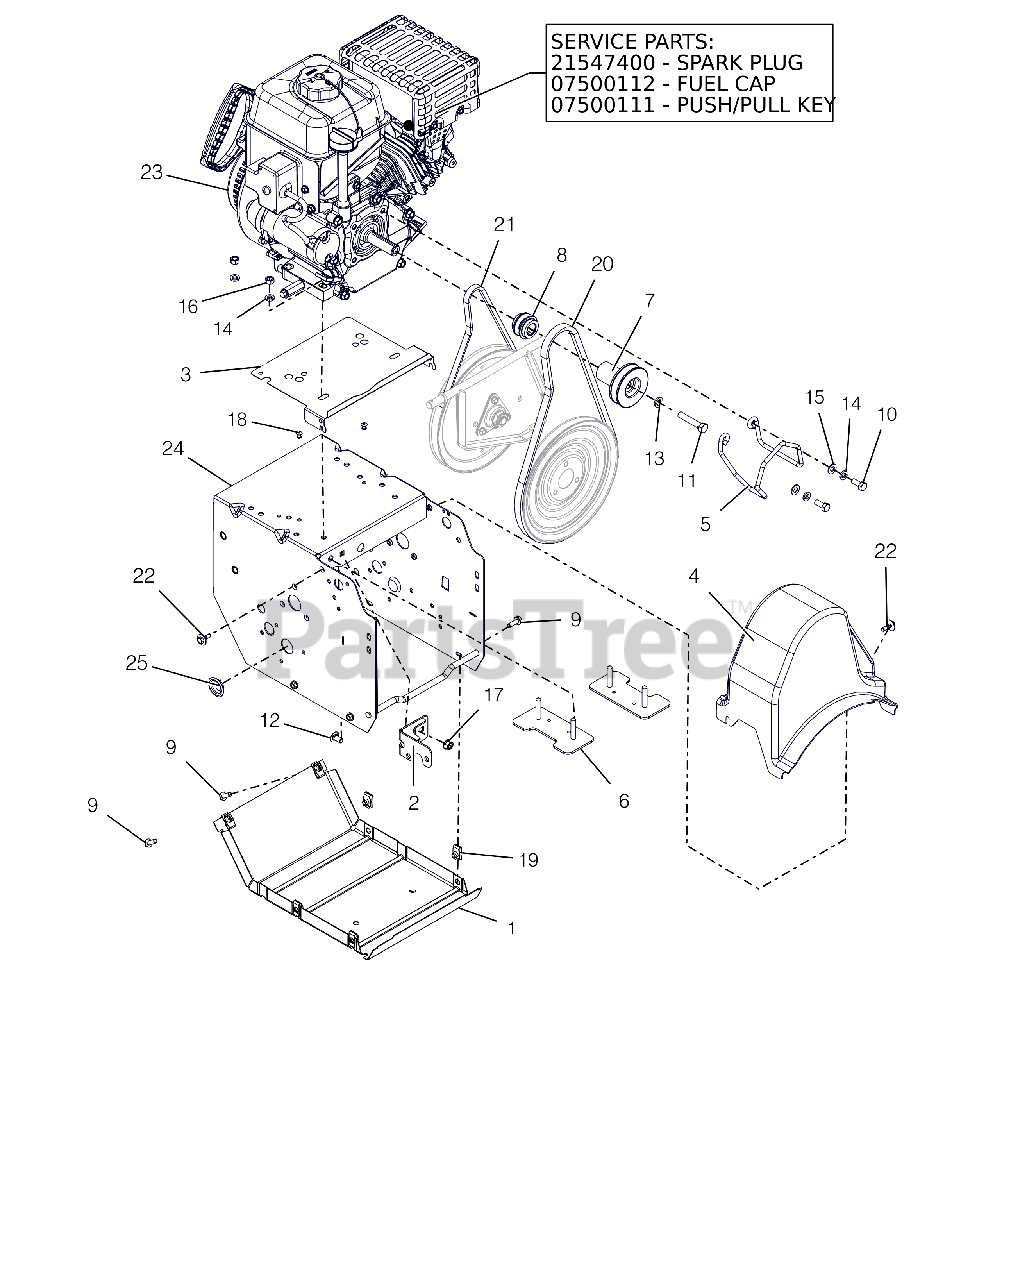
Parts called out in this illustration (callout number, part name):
1	COVER, BOTTOM
2	WELDMENT, FRAME BRACKET
3	BAFFLE, COMPACT
4	COVER, COMPACT BELT
5	FINGER, BELT
6	STRAP, ENGINE BOLT-WELDMENT
7	SHEAVE, AUGER 3/4 - PM
8	TRACTION SHEAVE HALF
9	BLT-HEX .25-20X.75 HWH YZ GR5
10	BLT-HEX .31-24X.75 YWZC GR5
11	BLT-HEX .38-24X2.0 YWZC
12	@BLT-RHDSSQNK .31-18X.62 G5YZ
13	@WSHR-LK .38X.094 REG YWZC
14	WSHR-LK .312X.097 HVY YWZC
15	@WSHR-FL-STL.344X.688X.065YWZC
16	@NUT-HEX .31-18 YWZC
17	@NUT-LK-TOP-FLG .31-18 YWZC
18	RVT-POP .187 YZ
19	NUT-RTNR .25-20X.56
20	V-BELT, HA-RAW EDGE
21	V-BELT, 3L-WRAPPED
22	SCR-TAP .25-20X.5 CAPTIVE
23	ENGINE, SNO-TEK 208 120V
23	PLUG, SPARK
23	CAP, FUEL TANK BLACK
23	KEY, PUSH/PULL LCT (2/PACKAGE)
24	FRAME, MAIN
25	PLUG, HOLE - 1.00" FLEXTEMP
